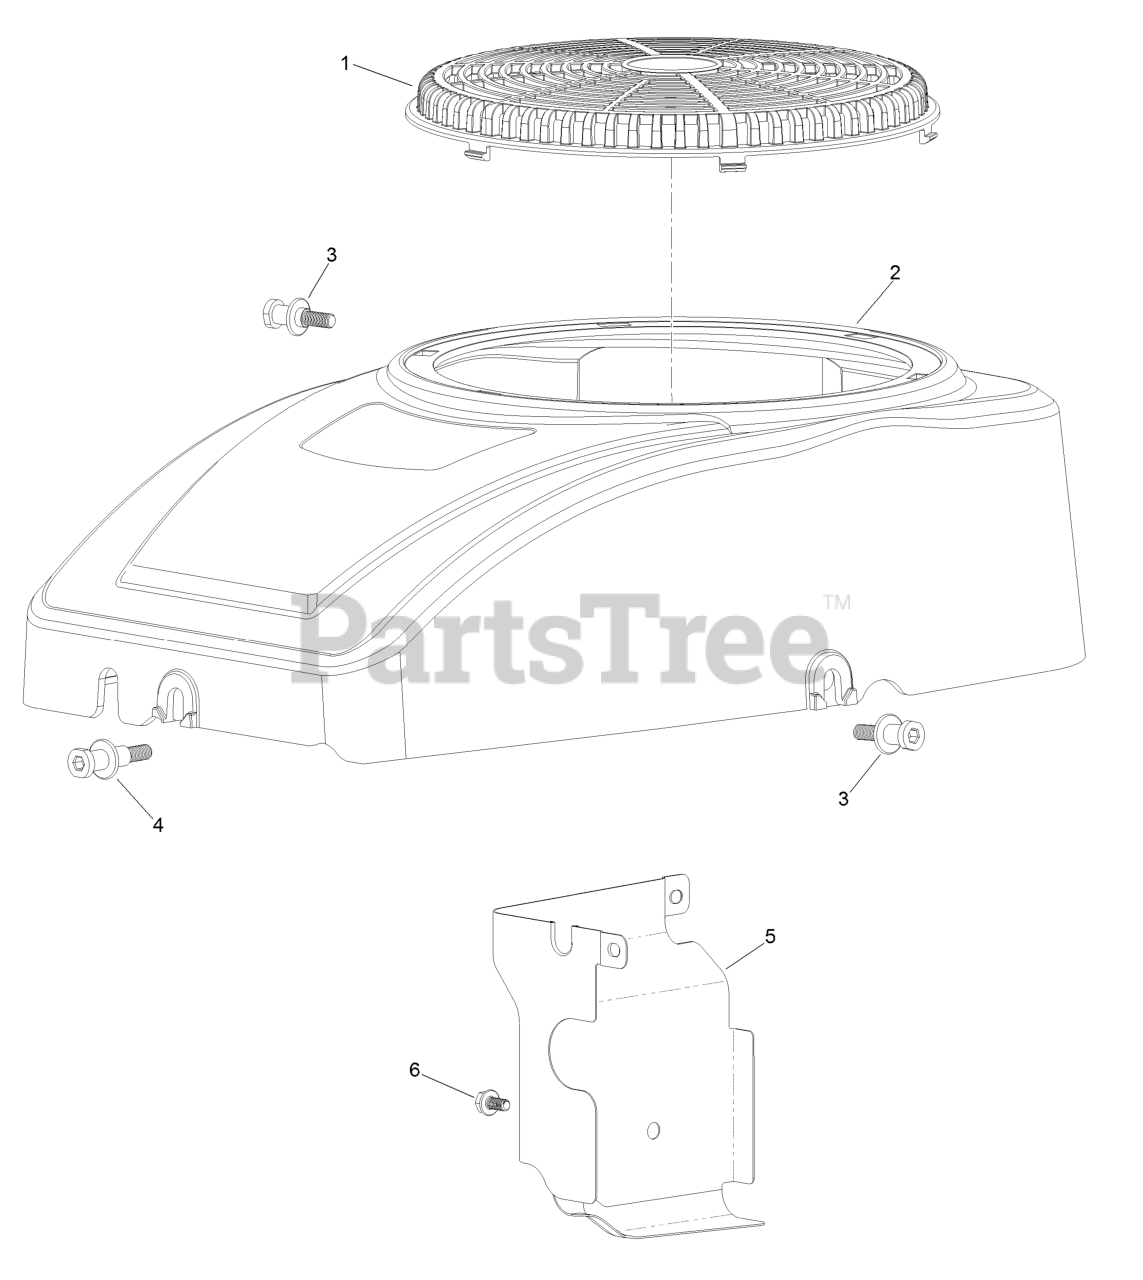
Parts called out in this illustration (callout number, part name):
1	SCREEN-STATIONARY
2	SHROUD-FAN
3	SCREW-SHOULDER, HH
4	SCREW-SHOULDER, HH
6	SCREW-HHF
